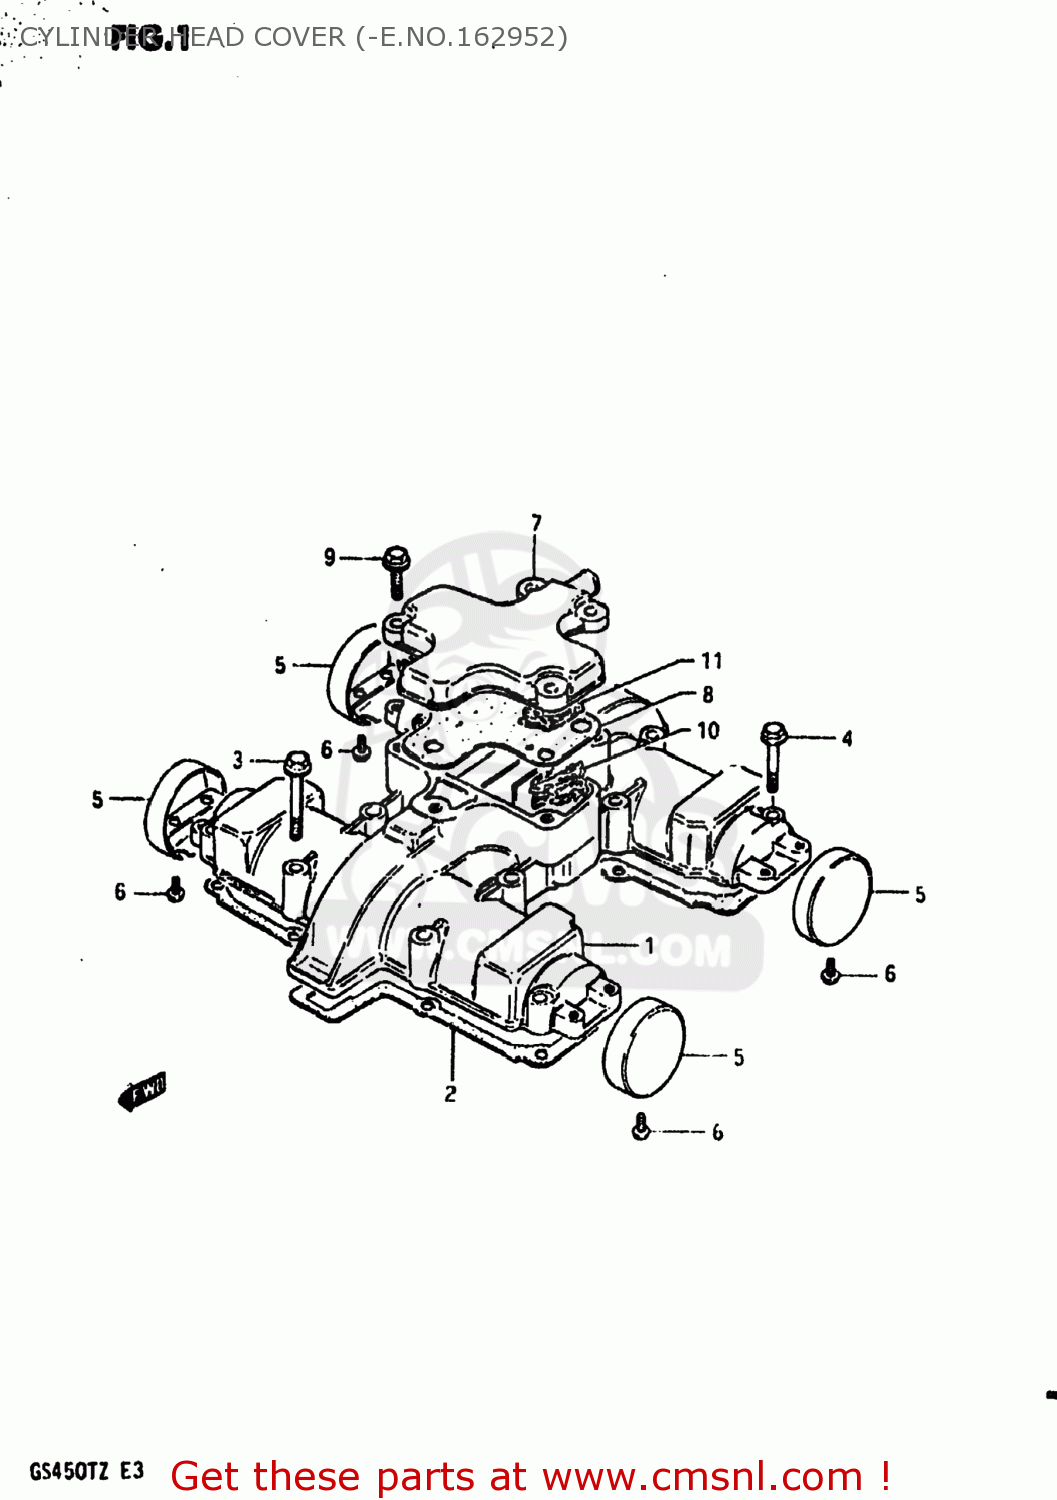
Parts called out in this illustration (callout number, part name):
1	COVER, CYLINDER HEAD
2	GASKET,CYLINDER HEAD COVER
3	BOLT
4	BOLT
5	CAP,CYLINDER HEAD COVER
6	SCREW
7	COVER,BREATHER
8	GASKET (MCA)
9	BOLT,REAR
10	COVER,BREATHER
11	SEPARATOR,OIL BREATHER
